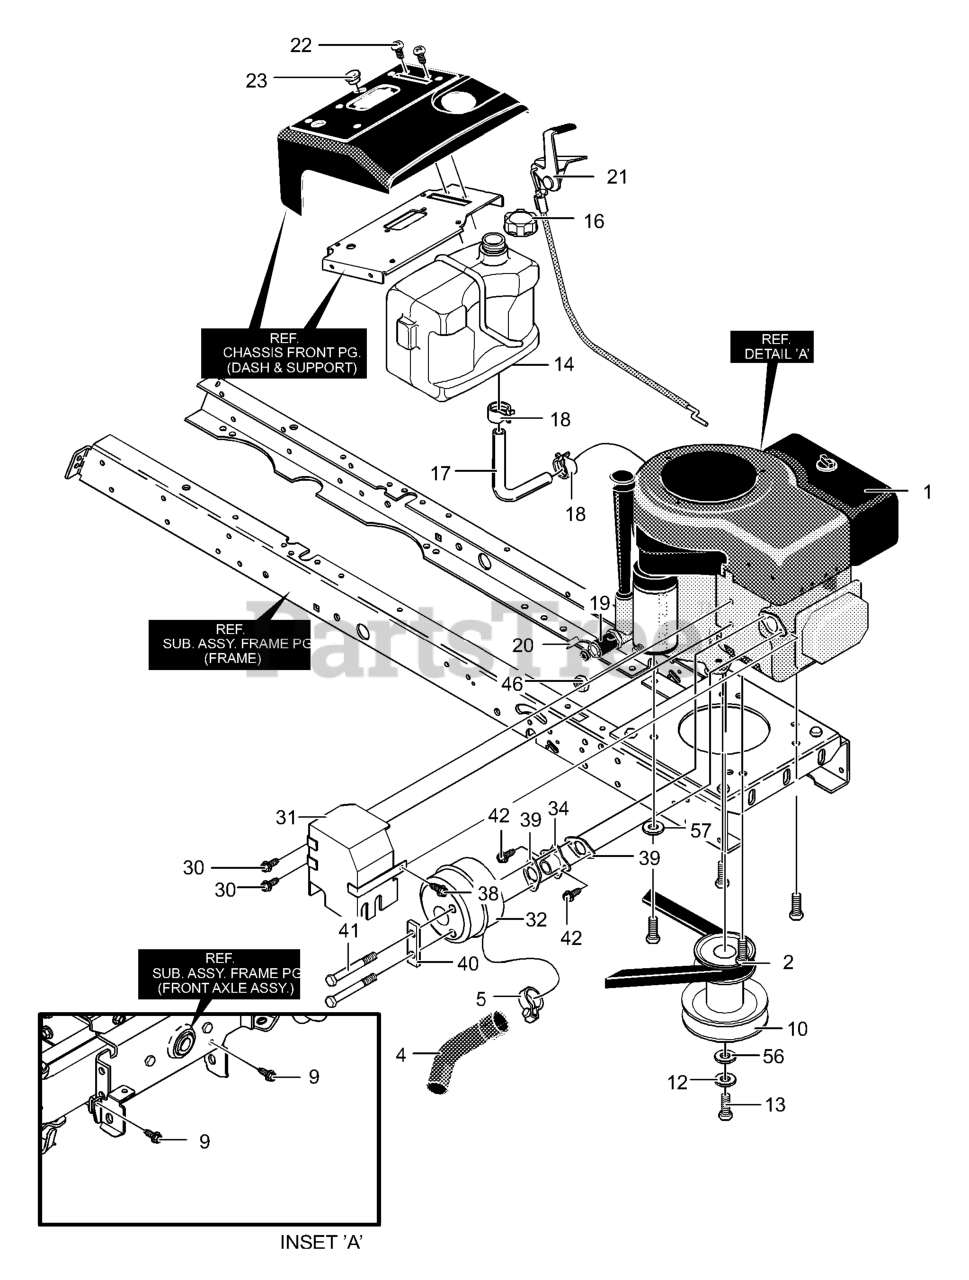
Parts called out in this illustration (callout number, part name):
1	ENGINE
2	BOLT 3/8 X 1.25
4	PIPE, EXHAUST
5	CLAMP ASSEMBLY
10	PULLEY, STACK
12	WASHER
14	TANK, FUEL
16	FUEL CAP
17	TUBING
18	CLAMP, FUEL LINE
19	OIL DRAIN VALVE ASSEMBLY
20	CAP, OIL DRAIN VALVE
21	THROTTLE, CONTROL
23	PLUG, DASH
31	HEAT SHIELD ASSEMBLY
31-1	SHIELD, HEAT B/S
31-2	RIVET, POP
31-3	BRACKET, RIGHT
31-4	BRACKET, LEFT
31-5	PLATE, HEAT SHIELD
32	MUFFLER, ROUND
34	MUFFLER ADAPTER
38	SCREW
39	GASKET, Exhaust
40	BRACKET, LOCK
46	NUT, 1/4-20
57	WASHER
